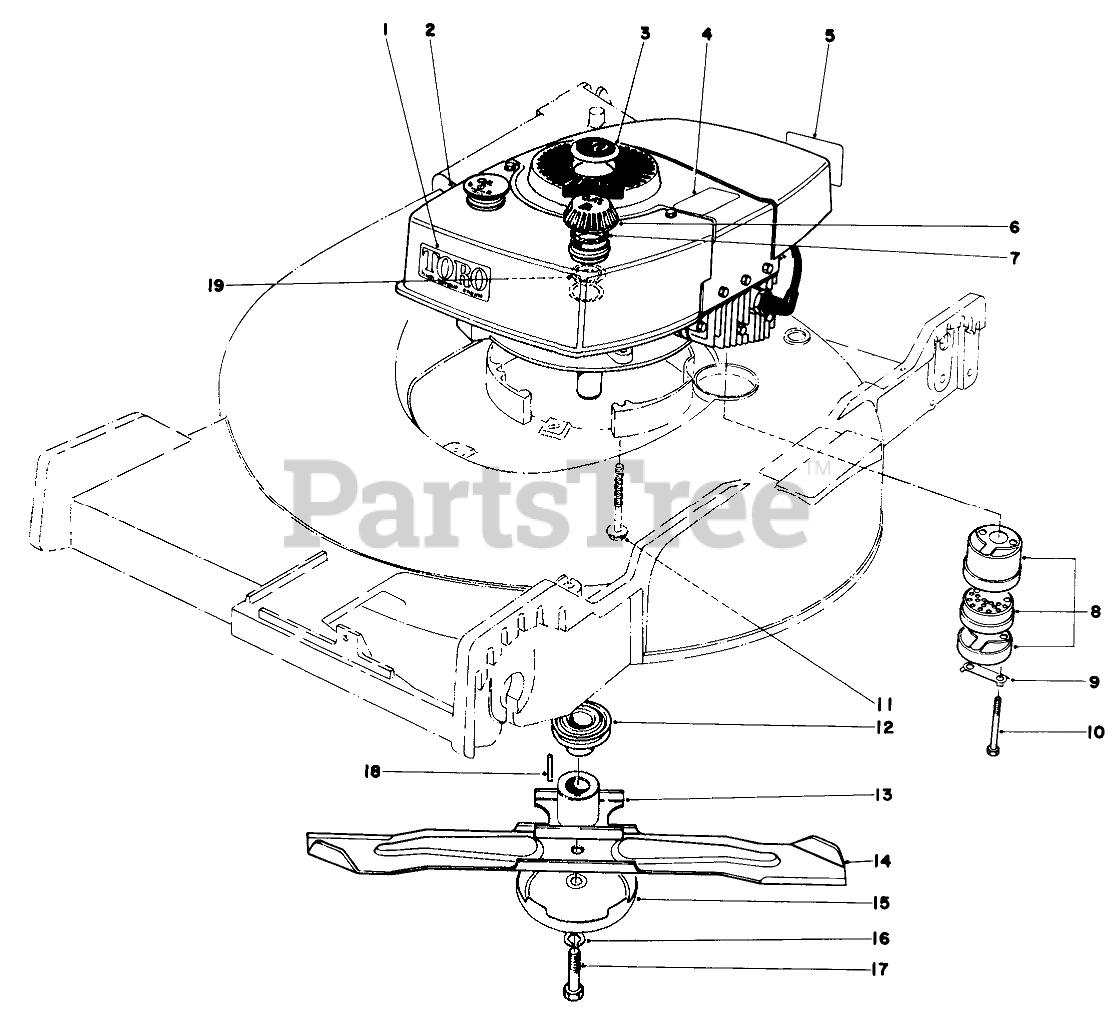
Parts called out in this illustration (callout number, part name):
1	High Torque
2	Engine
3	Plug Button
4	Decal Lockout
5	Decal Maintenance
6	Gas Cap Assembly (Incl. Ref. #7 & 19)
7	GASKET
8	Muffler Assembly (Incl. Ref. #9 & 10)
9	CLIP - LOCKING
10	SCREW-HH
11	3/8-16 X 2-3/4 CAPSCR
12	DRIVER PULLEY
13	BLADE RETAINER WA(BLACK)
14	Blade
15	AntiScalp Cup
16	WASHER-LOCK
17	BLADE SCREW
18	KEY-SQUARE
19	GAS CAP BAFFLE
